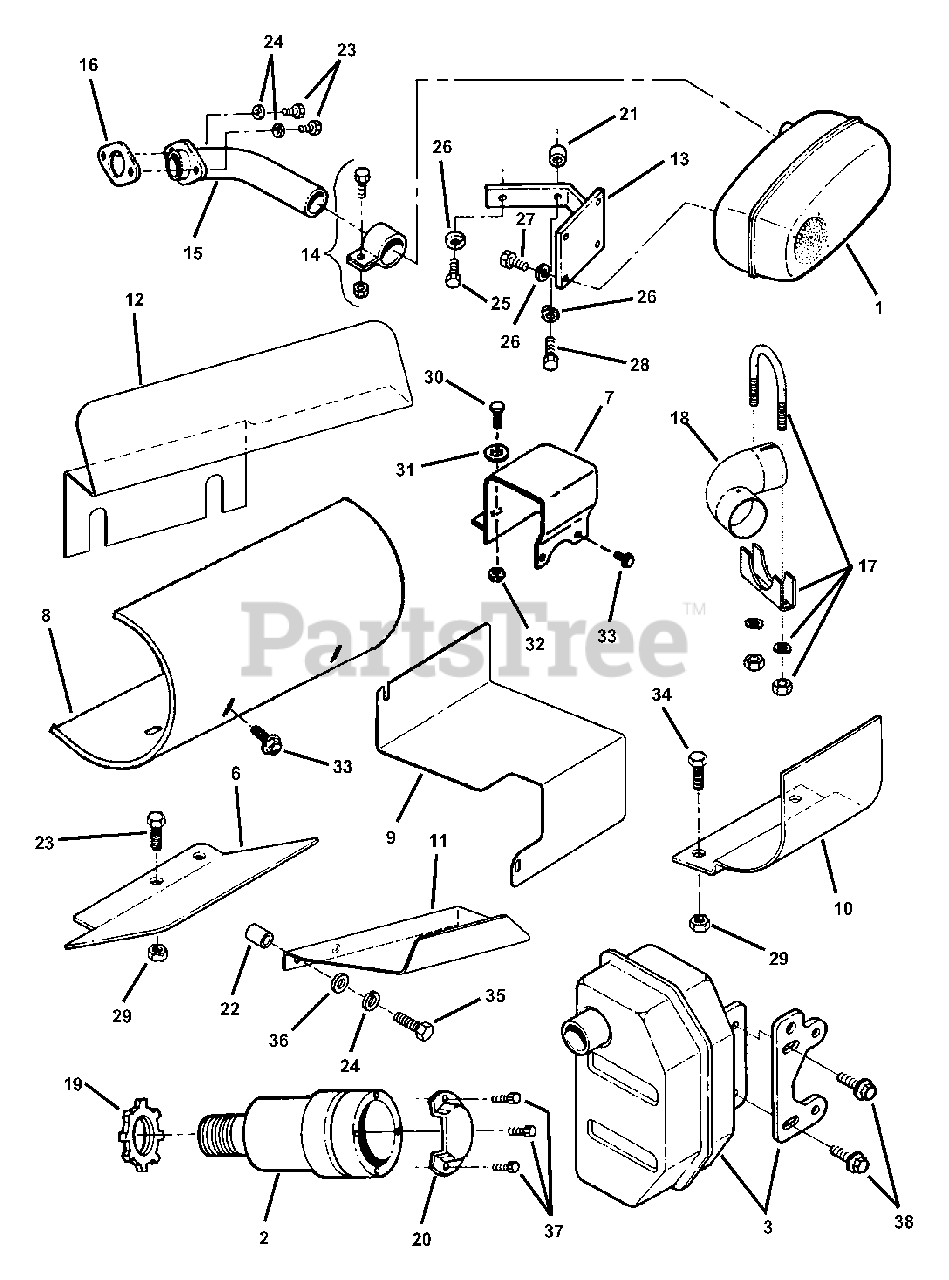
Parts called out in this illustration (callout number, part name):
1	MUFFLER, Super Lo-Tone
2	MUFFLER, Round Lo-Tone
3	MUFFLER GROUP
6	SHIELD, Heat
7	SHIELD, Heat
8	SHIELD, Heat
9	SHIELD, Heat
10	SHIELD, Heat
11	SHIELD, Heat
12	SHIELD, Heat
13	BRACKET, Muffler Mount
14	CLAMP, Muffler w/Bolt & Nut
15	TUBE, Exhaust Assembly
16	GASKET, Exhaust
17	ASSEMBLY, Clamp
18	ELBOW, Exhaust
19	RING, Locking
20	DEFLECTOR, Side Out
21	SPACER, Muffler Bracket
22	SPACER
23	SCREW, 5/16-18 x 3/4" Hex Head Cap, Grade 5
24	WASHER, 5/16" Split Lock
25	SCREW, 1/4-20 x 1" Hex Head Cap, Grade 5
26	WASHER, 1/4" Split Lock
27	SCREW, 1/4-20 x 5/8" Hex Head Cap, Grade 5
28	SCREW, 1/4-20 x 3/4" Hex Head Cap
29	NUT, 5/16-18 Hex Nyloc
30	SCREW, #10-24 x 1/2" Hex Head Machine
31	WASHER, #10 Flat
32	NUT, #10-24 Hex Center Lock
33	SCREW, #8-18 x 9/16" Hex Washer Self-Tap
34	SCREW, 5/16-18 x 3/4" Hex Head Cap, Grade 5
35	SCREW, M8 1.25 x .25 Hex Head Cap
36	WASHER, 3/8" Flat
37	SCREW, Muffler Deflector
38	SCREW, M6 x 16mm Hex Cap
